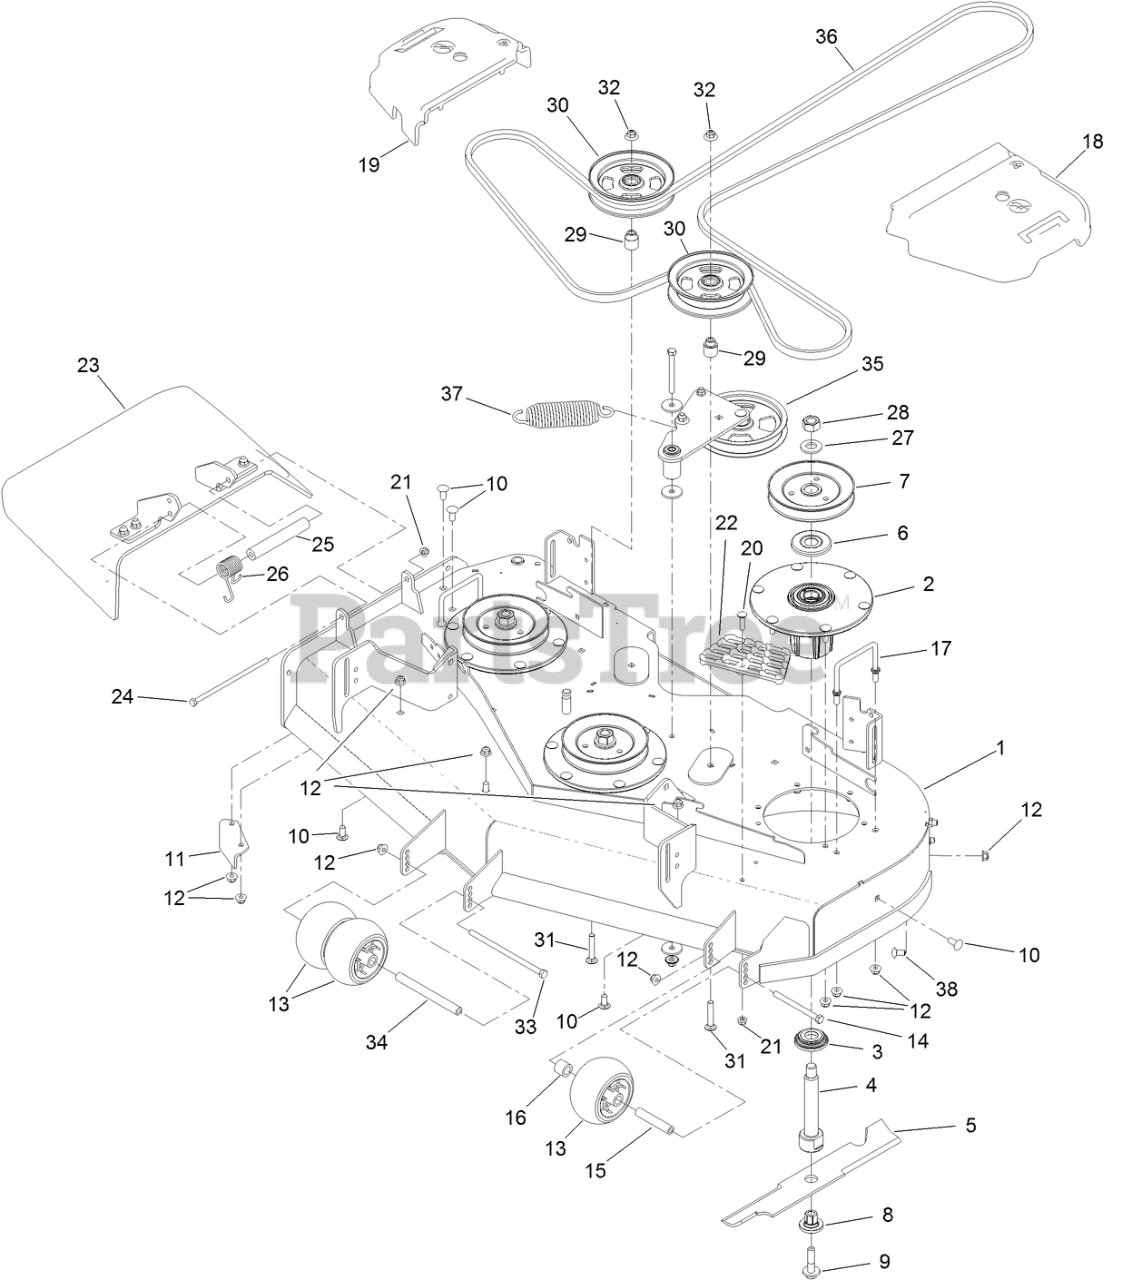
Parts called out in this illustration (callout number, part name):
1	DECK DECAL ASM
2	SPINDLE ASM
3	GUARD-BOTTOM
4	SHAFT-SPINDLE
5	BLADE-16.50 HIGH FLOW
6	GUARD-BEARING, TOP
7	SHEAVE,BLADE DRIVE 5.91
8	BUSHING-HEX
9	SCREW-SEMS
10	SCREW-CARR
11	BAFFLE-DISCHARGE
12	NUT-HF, NI
13	ROLLER-SCALP, ANTI
14	SCREW-HH
15	TUBE-SPANNER
16	TUBE-SPACER
17	WIREFORM-COVER
18	COVER-BELT, LH
19	COVER-BELT, RH
20	SCREW-CARR
21	NUT-HF, NI
22	STEP-DECK
23	RUBBER DEFLECTOR ASM
24	SCREW-HH
25	SPACER
26	SPRING-TORSION
27	WASHER
28	NUT-HEX
29	BUSHING, IDLER
30	PULLEY-IDLER, FLAT
31	SCREW-CARR
32	NUT-FLANGE, NI
33	SCREW-HH
34	SPACER-WHEEL
35	IDLER ARM ASM
36	BELT-V
37	SPRING-EXTENSION
38	SCREW-CARR
